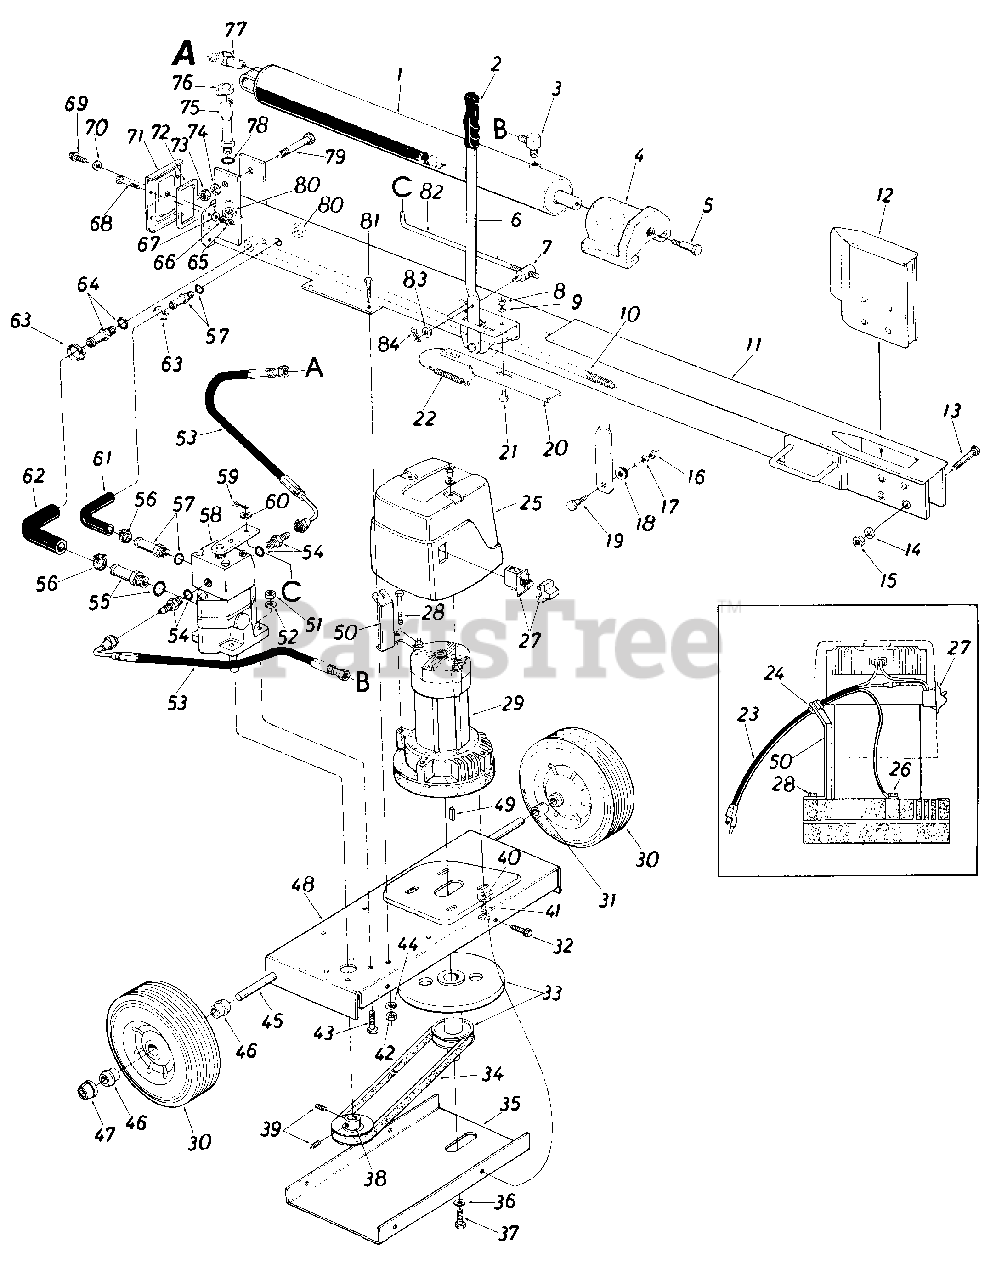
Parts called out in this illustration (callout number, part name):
1	2-1/2" Cyl. Ass'y. Comp.
2	Grip
3	90ø Elbow Adapter
4	Pusher Plate
5	Shoulder Bolt 5/8" Dia. x .660" Lg. 1/2-13 Thd.
6	Engagement Handle
7	Adjustment Ferrule
8	Hex Nut 5/16-18 Thd.*
9	L.-Wash. 5/16" I.D.*
10	Strainer Tube Ass'y.
11	Oil Tank Ass'y. Comp.
12	Wedge Assly.
13	Hex Bolt 5/8-18 x 3.50" Lg. (Grade 5)
14	L.-Wash. 5/8" I.D. *
15	Hex Nut 5/8-18 Thd.*
16	Hex Nut 3/8-16 Thd.*
17	L.-Wash. 3/8" I.D.*
18	Rubber Wash.
19	Shou Ider Bolt .498 x .340
20	Engagement Brkt.
21	Shoulder Bolt .437" Dia. x.180" Lg.
22	Extension Spring .50" O.D. x 4.25" Lg.
23	Cord with Plug
24	Cord Restraint
25	Motor Shroud
26	Hex Wash. Hd. Scr. 8-32 x .38" Lg. (Green)
29	Electric Motor
30	Wheel Ass'y. Comp. 10.0" x 2.75
31	Sleeve.632" I.D. x.875" O.D. x .90" Lg.
32	Hex Wash. Hd. Self Tap. Scr. 1/4-20 x .50" Lg.
33	Motor Pulley & Flywheel Ass'y.
34	"V"-Belt (4L) 1/2" V x 29" Lg.
35	Belt Cover
36	L.-Wash. 5/16" I.D.*
37	Hex Bolt 5/16-24 x .75" Lg. (Grade 5)
38	1/2 (4L) "V"-Pulley 5/8" I.D. x 3-1/2" O.D.
39	SetScr. 1/4-28 x.25" Lg.
40	Bell.-Wash. .345" I.D. x .88" O.D.
41	Hex Bolt 5/16-18 x .50" Lg. *
42	Hex Nut 5/16-24 Thd.*
43	Hex Bolt 5/16-18 x 1.00" Lg. *
44	L.-Wash. 5/16" I.D.*
45	Axle Shaft 5/8" Dia. x 25.5" Lg.
46	Flange Brg. w/Flats.631" I.D.
47	Push Cap 5/8" Dia. Rod
48	Frame-Motor
49	Sq. Key 3/16" x 3/16" x 1.50" Lg.*
50	Restraint Bracket
51	Hex Nut 5/16-18 Thd.*
52	L.-Wash. 5/16" I.D.*
53	High Pressure Hose
54	Adapter-or Boss to MJIC 9/16-18 to 7/16-20
55	Adapter 3/4" Tubing to 3/4-16 M Boss
56	Hose Clamp 5/8" I.D.
57	Adapter 1/2" Tube 9/16-18 or M Boss
58	Valve Ass'y.
59	Cotter Pin 3/32" Dia. x .75" Lg.*
60	Fl.-Wash. .344" I.D. x .62" O.D. x .063
61	Return Hose.50" I.D.
62	Suction Hose.75" I.D.
63	Hose Clamp 1/4" I.D.
64	Adapter 1.0" Tube 1-1/16-12 "O"-Ring
65	Hex Nut 5/16-18 Thd.*
66	L.-Wash . 5/16" I.D. *
67	Fl.-Wash. .343" I.D. x .687" O.D. x .062
68	Hex Bolt 5/16-18 x 1.50" Lg. *
69	Hex Hd. Tap Scr. 5/16"
70	Gasket
71	End Plate
72	Gasket
73	Hex Nut 3/4" Thd.*
74	L.-Wash. 3/4" I.D.*
75	Filler Tube Ass'y.
76	Oil Fill Cap
77	45ø Male Adapter 7/16-20 MJ-1/4-18 NP
78	"O"-Ring .92" I.D. x 1.16" O.D. x .116 Dia.
79	Hex Bolt 3/4" x 4.0" Lg.
80	Hex Nut 11/16-1 Thd.
81	Hex Bolt 5/16-24x 1.00" Lg. (Grade 5)
82	Engagement Rod 16.75" Lg.
83	Fl.-Wash. .344" I.D. x .62" O.D. x .063
84	Hair Pin Cotter 5/16" Dia.
